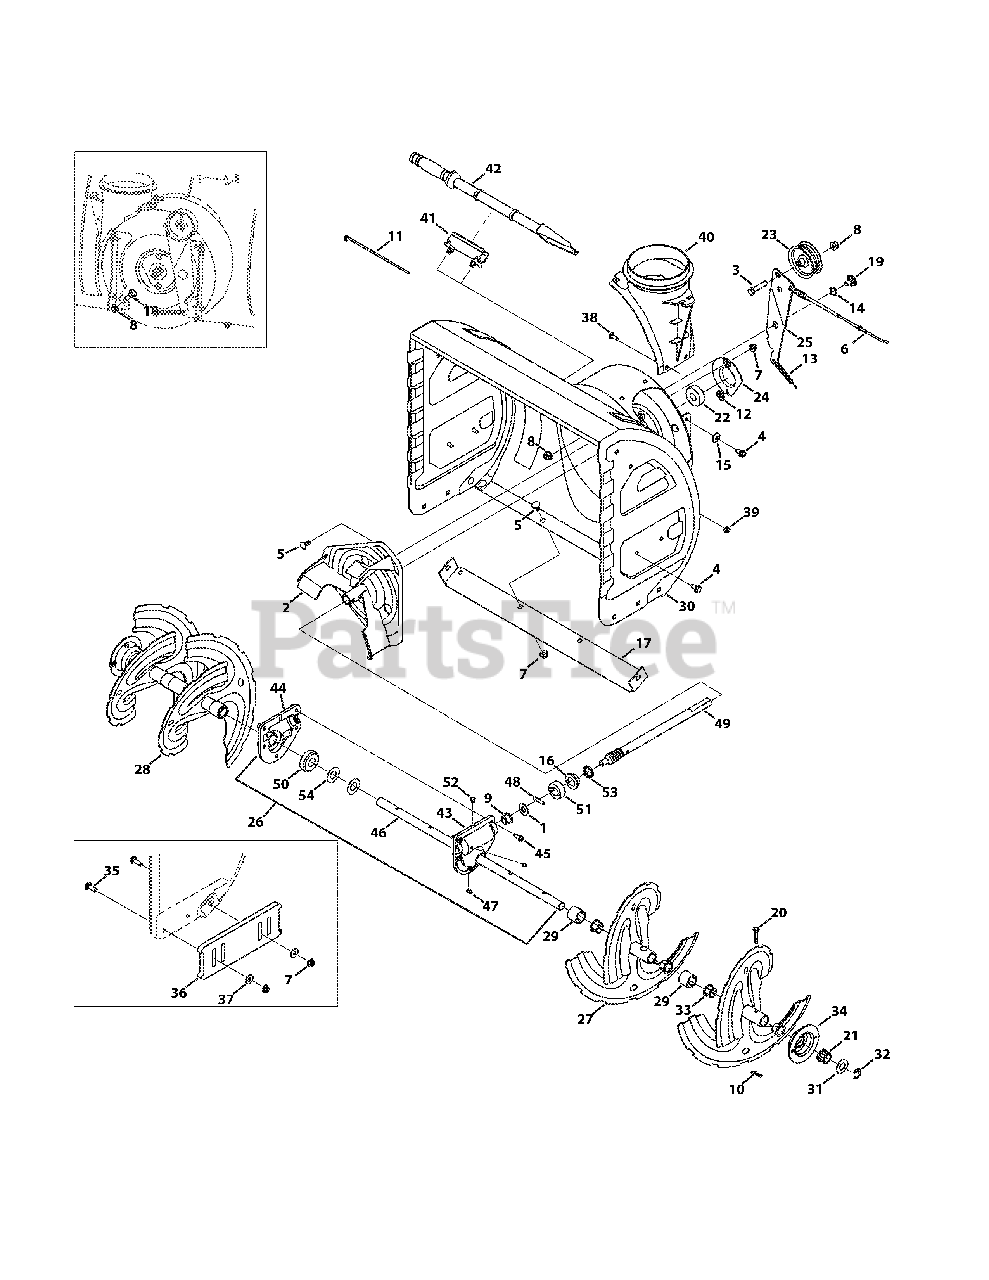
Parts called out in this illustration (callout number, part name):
1	Flat Washer, .51 x 1.12 x .06
2	Impeller Assembly
3	Hex Bolt, 3/8-16 x 1.75
4	Screw, 5/16-18 x .750
5	Carriage Bolt, 5/16-18 x .750
6	Auger Clutch Cable
7	Flange Lock Nut, 5/16-18
8	Flange Lock Nut, 3/8-16
9	Flange Bearing, .50 x .75 x .59
10	Bow Tie Cotter Pin
11	Cable Tie
12	Push-On Nut, .25 Dia.
13	Extension Spring, .38 OD x 4.59
14	Wave Washer, .625 x .885 x .0175
15	Bell Washer, .340 x .872 x .060
16	Flange Bearing, .75 x 1.00 x .59
17	Shave Plate, 28"
18	Shoulder Screw, 3/8-16 x .496 x .336
19	Shoulder Screw, 3/8-16 x .625 x .17
21	Hex Flange Bearing
22	Flange Ball Bearing, .75 x 1.85
23	Flat Idler Pulley
24	Bearing Housing
25	Auger Idler Bracket
26	Gearbox Assembly, Auger, 28"
27	Spiral Assembly - LH
28	Spiral Assembly - RH
29	Spacer, 1.25 x .75 x 1.00
30	Auger Housing, 28"
31	Flat Washer, .76 x 1.49 x .06
32	E-Ring, .750
33	Flange Bushing, .800 x .910
34	Hex Bearing Housing
35	Spacer, Carriage, 5/16-18 x 1.00
36	Deluxe Slide Shoe
37	Washer, Flat, .349 x .879 x .063
38	Carriage Screw, 1/4-20 x 0.75
39	Flange Lock Nut, 1/4-20
40	Chute Adapter
41	Clean-out Tool Mtg. Bracket
42	Clean-Out Tool
43	Housing Assembly - RH
44	Housing Assembly - LH
45	Screw, 1/4-20 x 0.75
46	Axle, Auger, 28"
47	Hi-Pro Key
48	Dowel Pin, .25OD x 1.25
49	Worm Shaft
50	Worm Gear, 20T
51	Thrust Collar
52	Plug, 1/4 x .437
53	Oil Seal, .75 x 1.131 x .188
54	Flat Washer, .76 x 1.5
